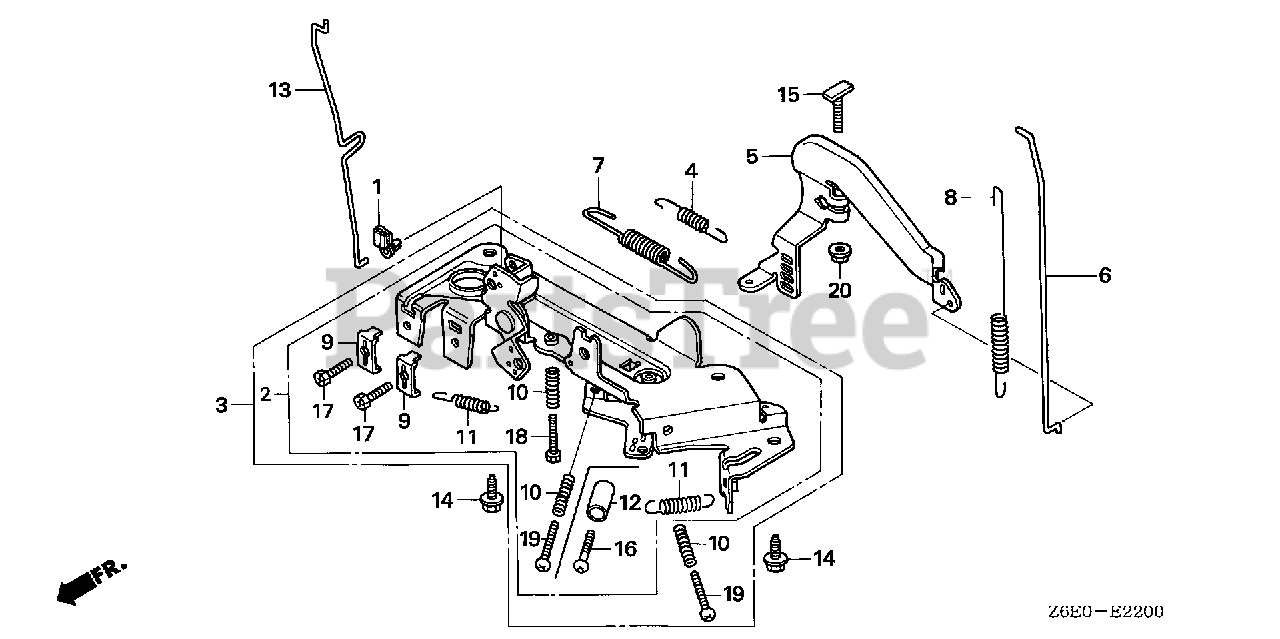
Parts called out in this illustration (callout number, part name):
1	JOINT, ROD
2	CONTROL ASSY.
4	SPRING, STARTER
5	ARM, GOVERNOR
6	ROD, GOVERNOR
7	SPRING, GOVERNOR
8	SPRING, THROTTLE RETURN
9	HOLDER, CABLE
10	SPRING, CONTROL ADJUSTING
11	SPRING, CABLE RETURN
12	COLLAR, STOPPER
13	ROD, CHOKE CONTROL
14	BOLT, FLANGE (6X14) (CT200)
15	BOLT, GOVERNOR ARM
16	SCREW, RECESSED (5X28) (BLACK)
17	BOLT, RECESSED (5X16)
18	BOLT, RECESSED (5X25)
20	NUT, FLANGE (6MM)
